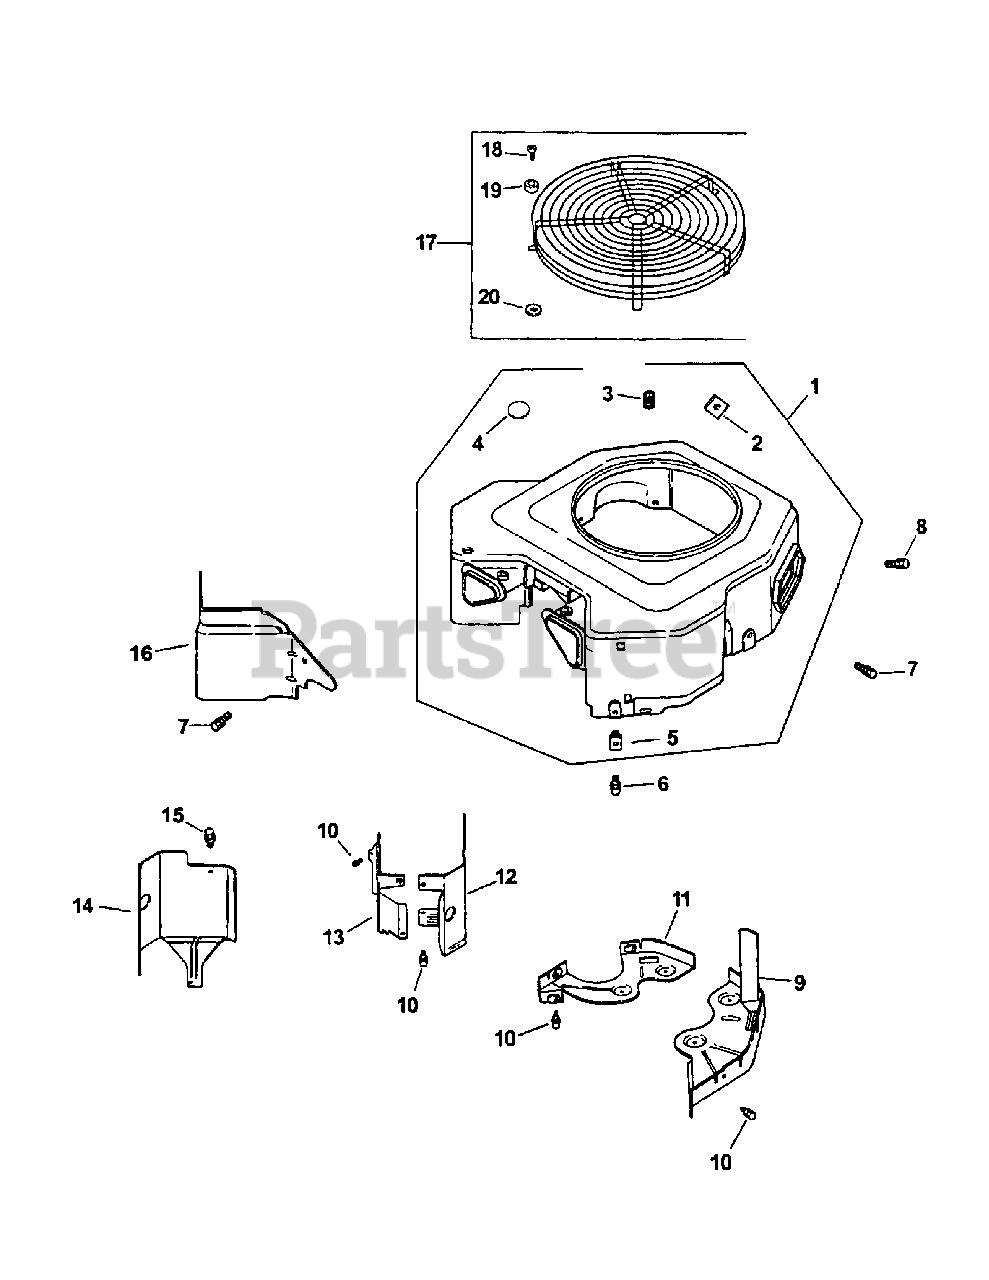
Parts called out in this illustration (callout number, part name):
1	Housing, Blower
2	Nut, Plastic
3	Screw, Set
4	Plug, Button 9/16"
5	Nut, Plastic
6	Screw, Hex Flange
7	Screw, Hex Flange
8	Screw, Hex Flange
9	Plate, Backing - #2 Side
10	Screw, Hex Flange
11	Plate, Backing - #1 Side
12	Baffle, Cylinder Barrel - #2 Side
13	Baffle, Valley - #1 Side
14	Baffle, Cylinder Barrel - #1 Side
15	Screw, Hex Flange
16	Baffle, Valley - #2 Side
17	Kit, Guard
18	Screw, Pan Head
19	Spacer
20	Washer, Plain 1/4"
